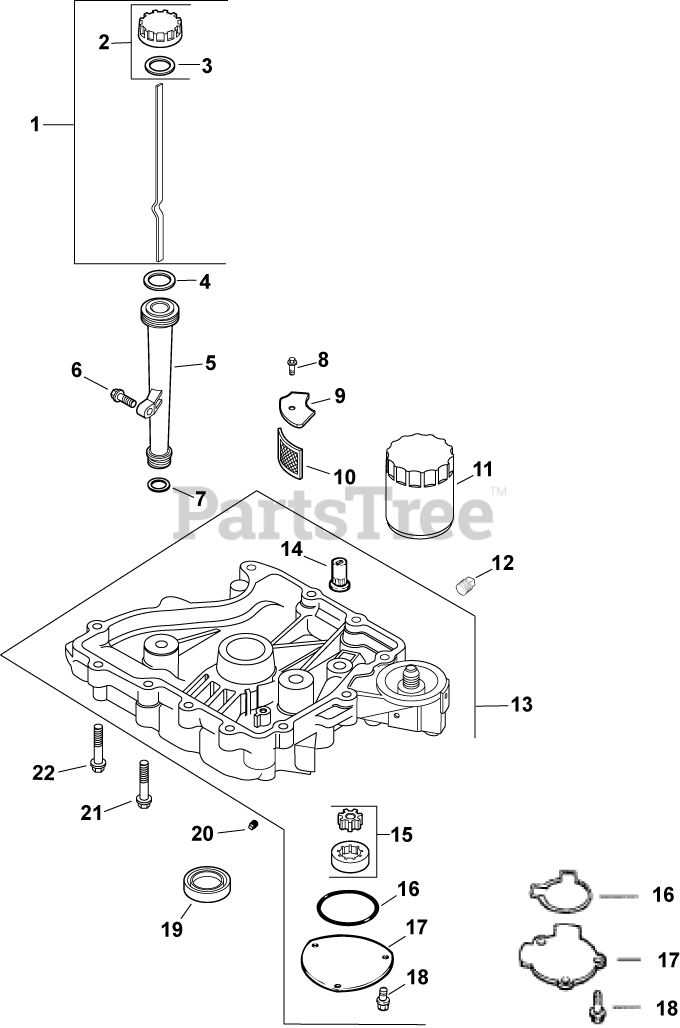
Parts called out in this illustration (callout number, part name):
1	DIPSTICK/CAP ASSY (BLACK)
2	KIT, OIL FILL CAP (BLACK)
3	O-RING, DIPSTICK
4	O-RING, UPPER OIL FILL TUBE
5	TUBE, OIL FILL USE 25 123 07-S
6	SCREW, FLG THD FRM M5X.8X20-(#25086399S)
7	O-RING, LOWER OIL FILL TUBE
8	SCREW,FLG THD FRM M5X0.8X16-(#25086398S)
10	SCREEN, OIL-USE 24 162 26-S
11	OIL FILTER
12	PLUG, SQ HD PIPE 3/8"
14	VALVE, OIL PRESSURE RELIEF
15	PUMP ASSEMBLY, OIL
16	O-RING (2.5" DIA)
17	COVER, OIL PUMP
18	SCREW,FLG THD FRM M5X0.8X16-(#25086398S)
19	SEAL, OIL
20	PLUG, PIPE 1/8 NPTF-SQ.HD.
21	SCREW, HEX FLANGE -USE 24 086 17-S
22	SCREW, FLG M8X1.25X45
1203204-S	SEAL, OIL-PUMP COVER
